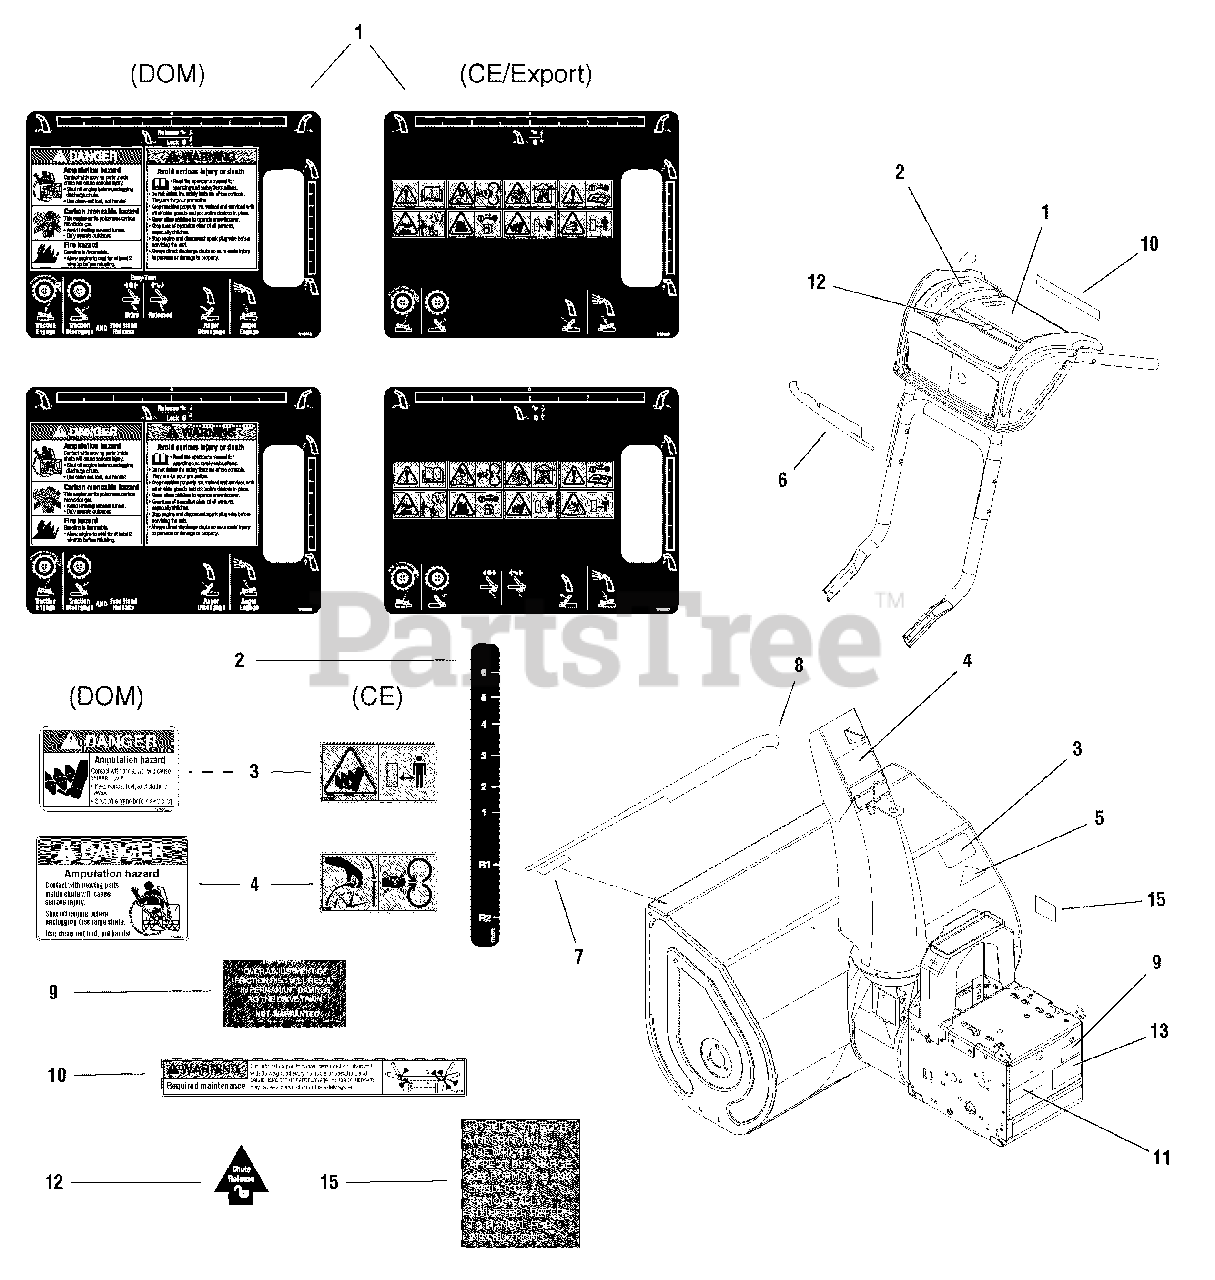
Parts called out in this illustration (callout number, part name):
1	DECAL, Dashboard Standard Drive
1	DECAL, Dashboard EZ Turn
2	DECAL, Shift 1,2,3,4,5,6 R1 R2
3	DECAL, Danger Avoid Injury From Auger
3	DECAL, Impeller Warning
4	DECAL, Danger Amputation Hazard
4	DECAL, Chute Warning
5	DECAL, Opei Certified ANSI
6	DECAL, SMI Dash Swoosh
7	DECAL, SMI 9528L
7	DECAL, SMI 8526L
7	DECAL, SMI 10530L
7	DECAL, SMI 11532L
8	DECAL, SMI Stripe 27.07 Long
8	DECAL, SMI Stripe 25.09 Long
8	DECAL, SMI Stripe 29.00 Long
8	DECAL, SMI Stripe 31.00 Long
9	DECAL, Over Adjustment of Friction Disc
10	DECAL, Warning Lubrication
11	DECAL, Touch Up Paint Orange, Black, Red
12	DECAL, Chute Release Arrow
13	DECAL, ID Plate
15	DECAL, Belt Stretch & Adjustment
